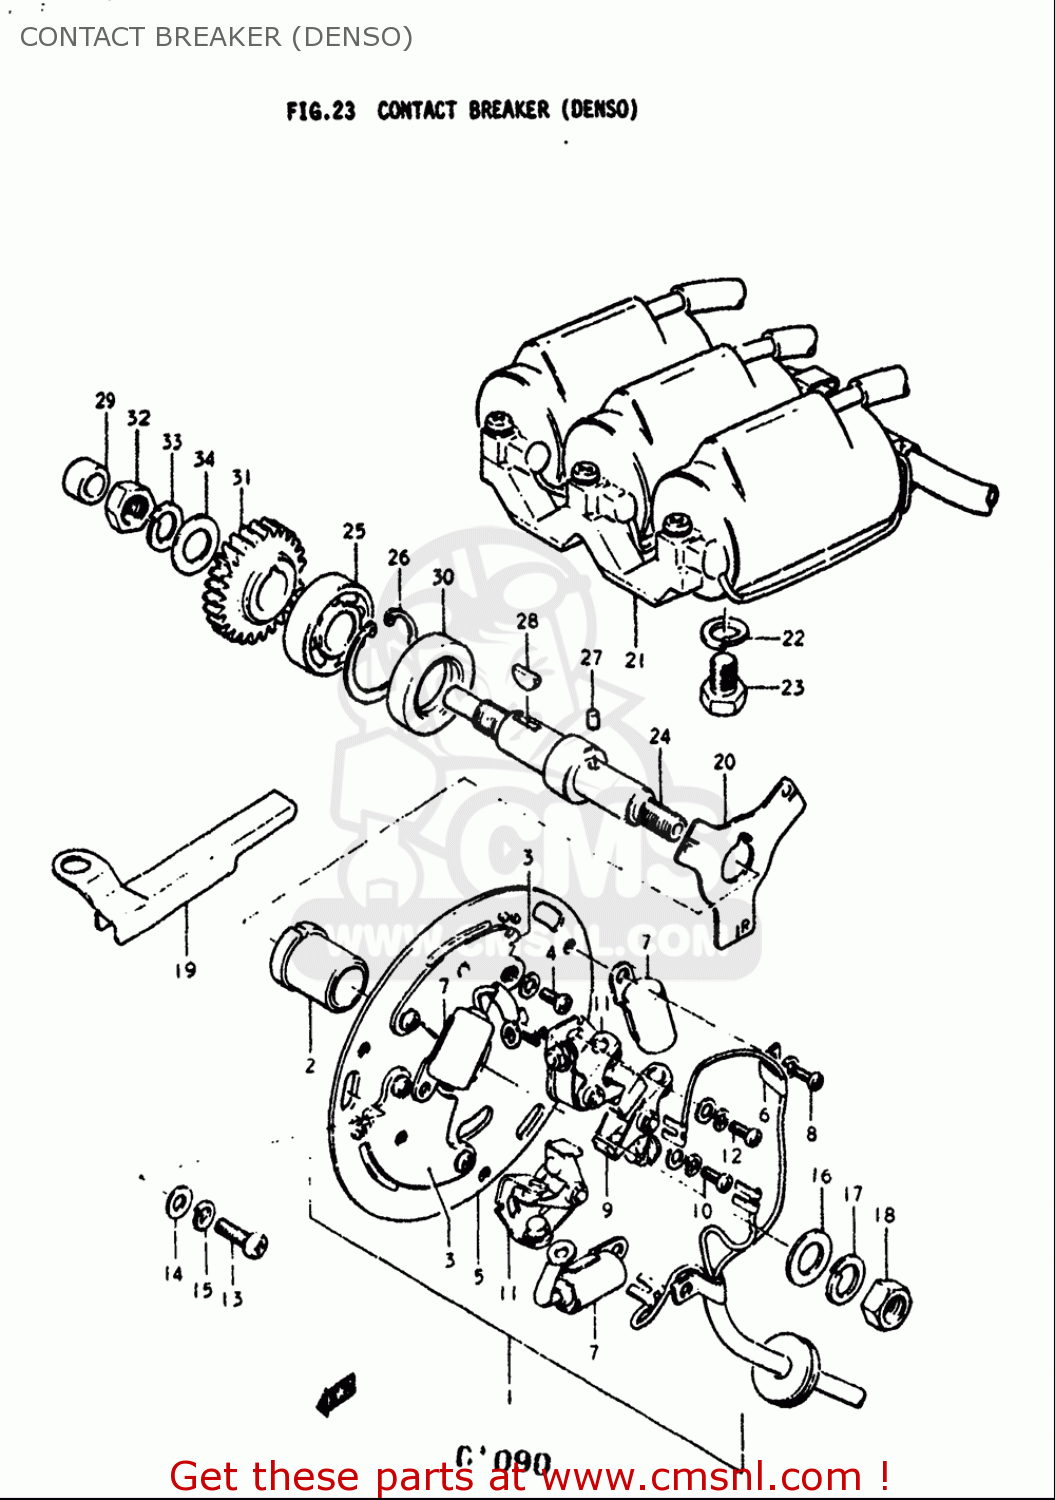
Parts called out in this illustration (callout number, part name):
3	SHIFT PLATE, CONTACT POINT
4	SCREW 4X6
7	CONDENSER
8	SCREW
9	POINT ASSY
10	SCREW 4X6
11	POINT ASSY
12	SCREW 4X6
13	SCREW(5X12)
14	WASHER
15	WASHER,LOCK
16	WASHER
17	WASHER,LOCK
18	NUT
22	WASHER,LOCK
23	BOLT
25	BEARING
26	CIRCLIP
27	PIN
28	KEY
30	SEAL,OIL(20X35X7)
31	GEAR,BREAKER CAMSHAFT DRIVEN
32	NUT
33	WASHER,LOCK
34	WASHER
